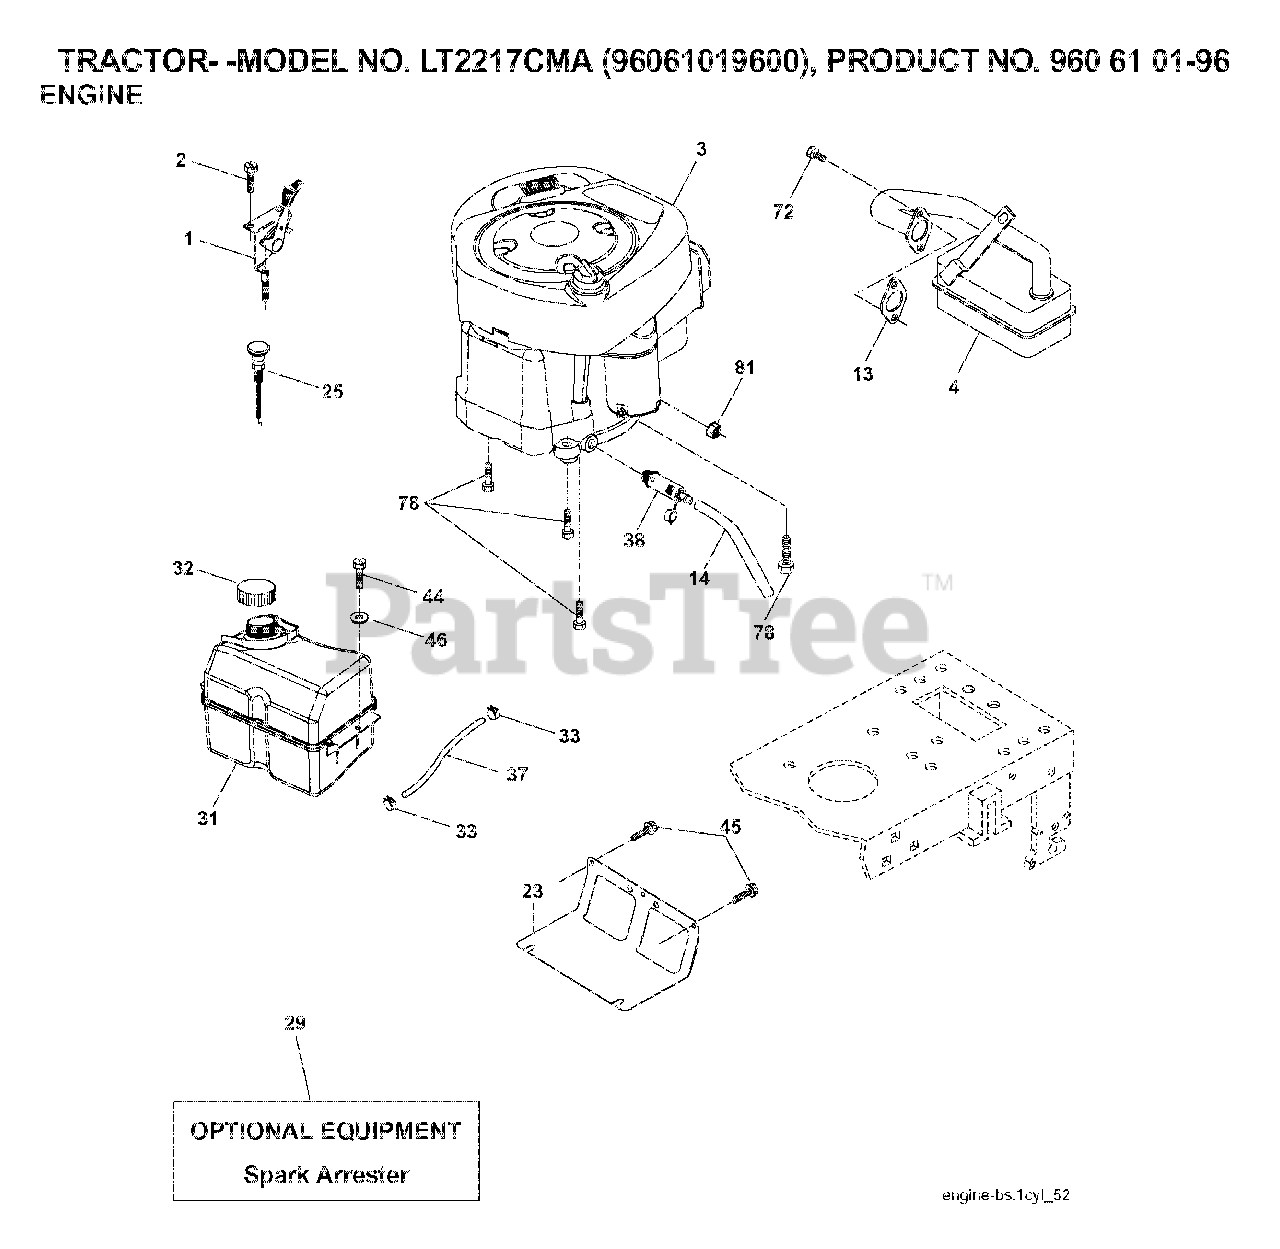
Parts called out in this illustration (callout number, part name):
1	CONTROL TH/CH FLAG
2	SCREW
13	REPL BY 532 27 22-93
14	TUBE, DRAIN OIL ASM.
23	SHEILD.BROWNING.DBR.GUARD
29	ARRESTER SPARK (OPTIONAL)
31	TANK FUEL
32	FUEL CAP
33	HOSE CLAMP
37	LINE.FUEL.20
38	PLUG DRAIN OIL EASY
44	SCREW HEXWSHR 1/4-20X3/4
45	SCREW, 3/8-16X3/4
72	SCREW.SOCKET HD.5/16-1
78	SCREW.3/8-16
81	NUT
